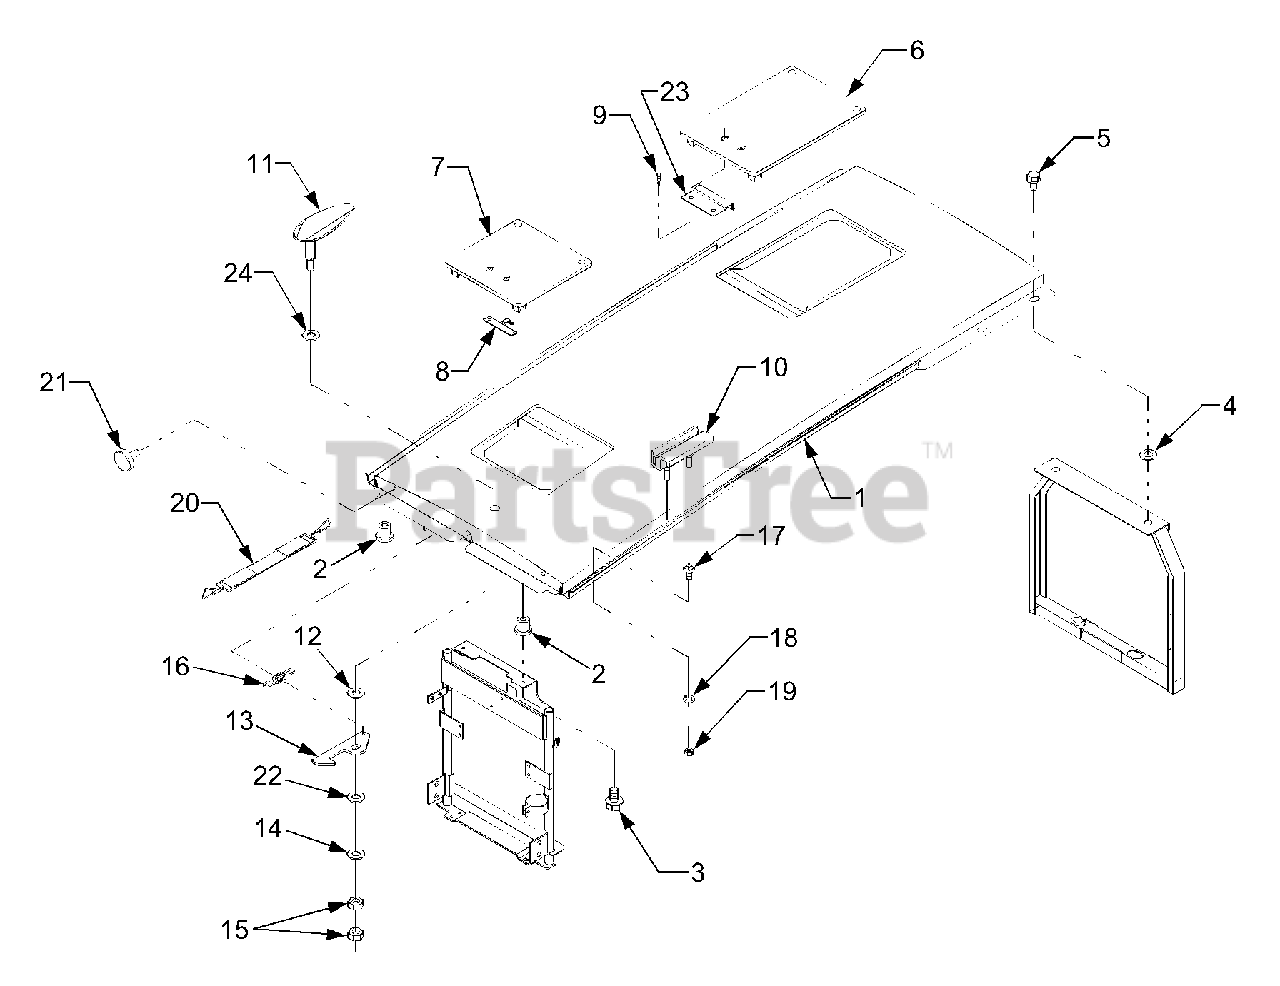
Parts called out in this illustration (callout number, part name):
1	Bonnet (Upper)
2	Rubber, Cushion
6	Cover 2 Ass'y
7	Cover(Aux.) Ass'y
9	Screw, Tapping
10	Cushion, Bonnet
11	Handle, Bonnet Lock
13	Plate, Front Grill
14	Washer, Plain
18	Washer, Spring
20	Hook Ass'y
